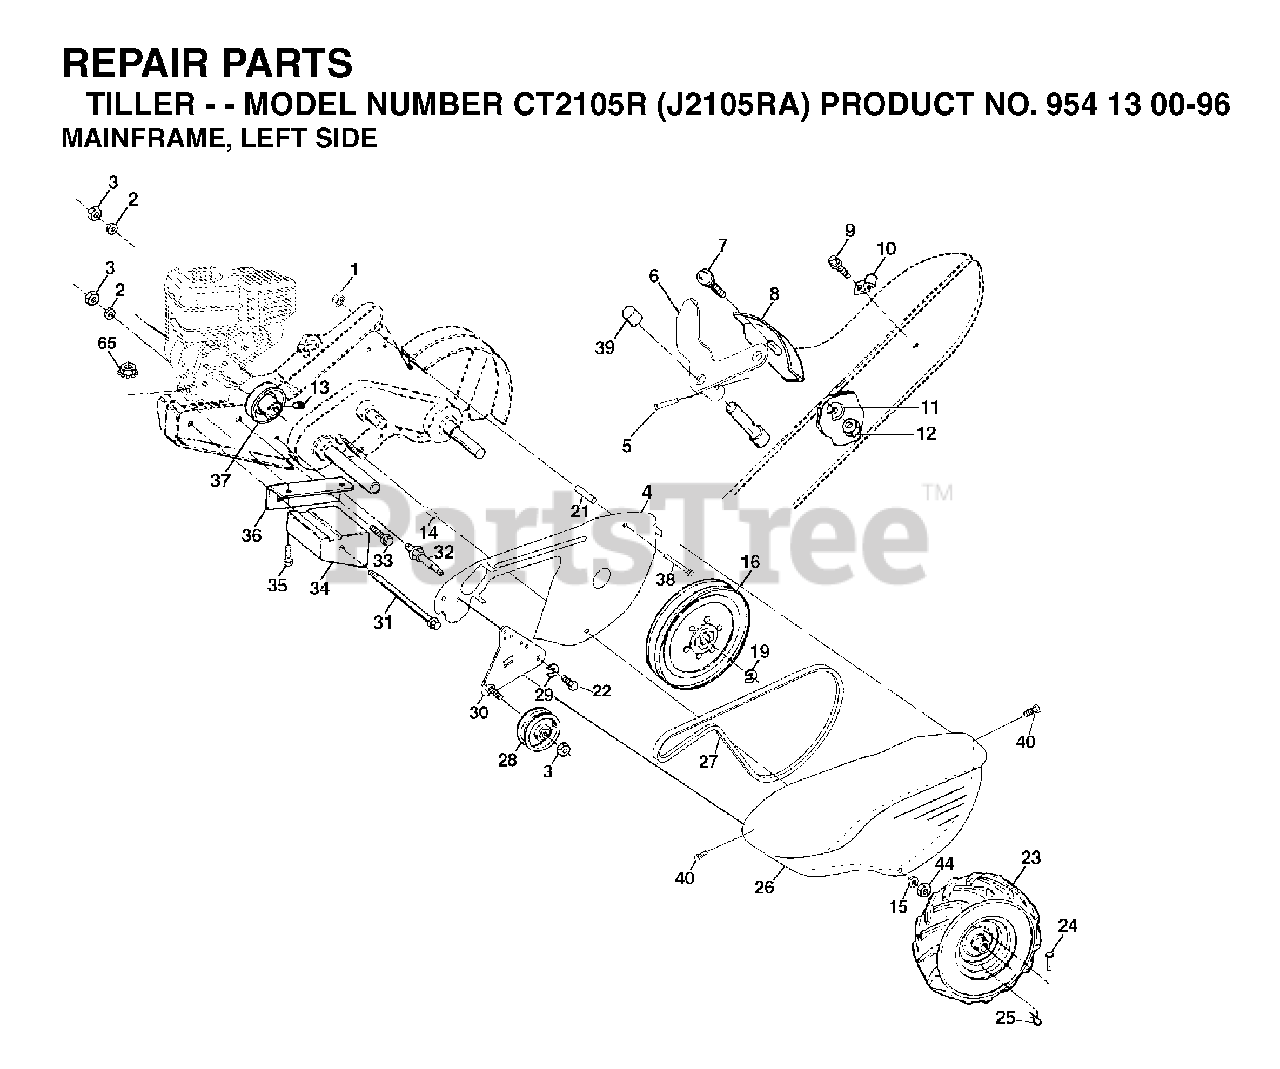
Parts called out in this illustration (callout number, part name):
1	NUT
2	WASHER, LOCK 3/8
3	NUT.HEX.3/8-16UNC
5	PIN.SPIROL.FLARED
6	LEVER ASM CRT
9	TAPPING SCREW
10	CONDUIT CLIP T
11	LOCKWASHER
12	NUT
13	SET SCREW **
14	SPACER-SPLIT.327 X .42
15	WASHER
16	SHEAVE, TRANSMISSION
19	RETAINING RING LT
21	SPACER CRT
24	RIVET,DRILLED
25	RETAINER M
27	V-BELT
28	PULLEY-IDLER TI
29	KLIP RING
30	BRACKET.ASM.IDLER
31	BOLT.FIN.HEX.3/8-16UNC
32	SHIFT ARM CRT
33	BOLT
34	COUNTERWEIGHT.LH.CRT
36	BRACKET LH CRT
37	ENGINE PULLEY
38	BOLT
39	CAP.PLUNGER.BLACK
40	SCREW.HEX.WSH.SLT.#10-24X.50
44	NUT.71038.31-18.HEX.NYLOCK
65	LOCKNUT-FLANGE 5/16-18
5321243-66	RIM
5321247-18	VALVE STEM LT
